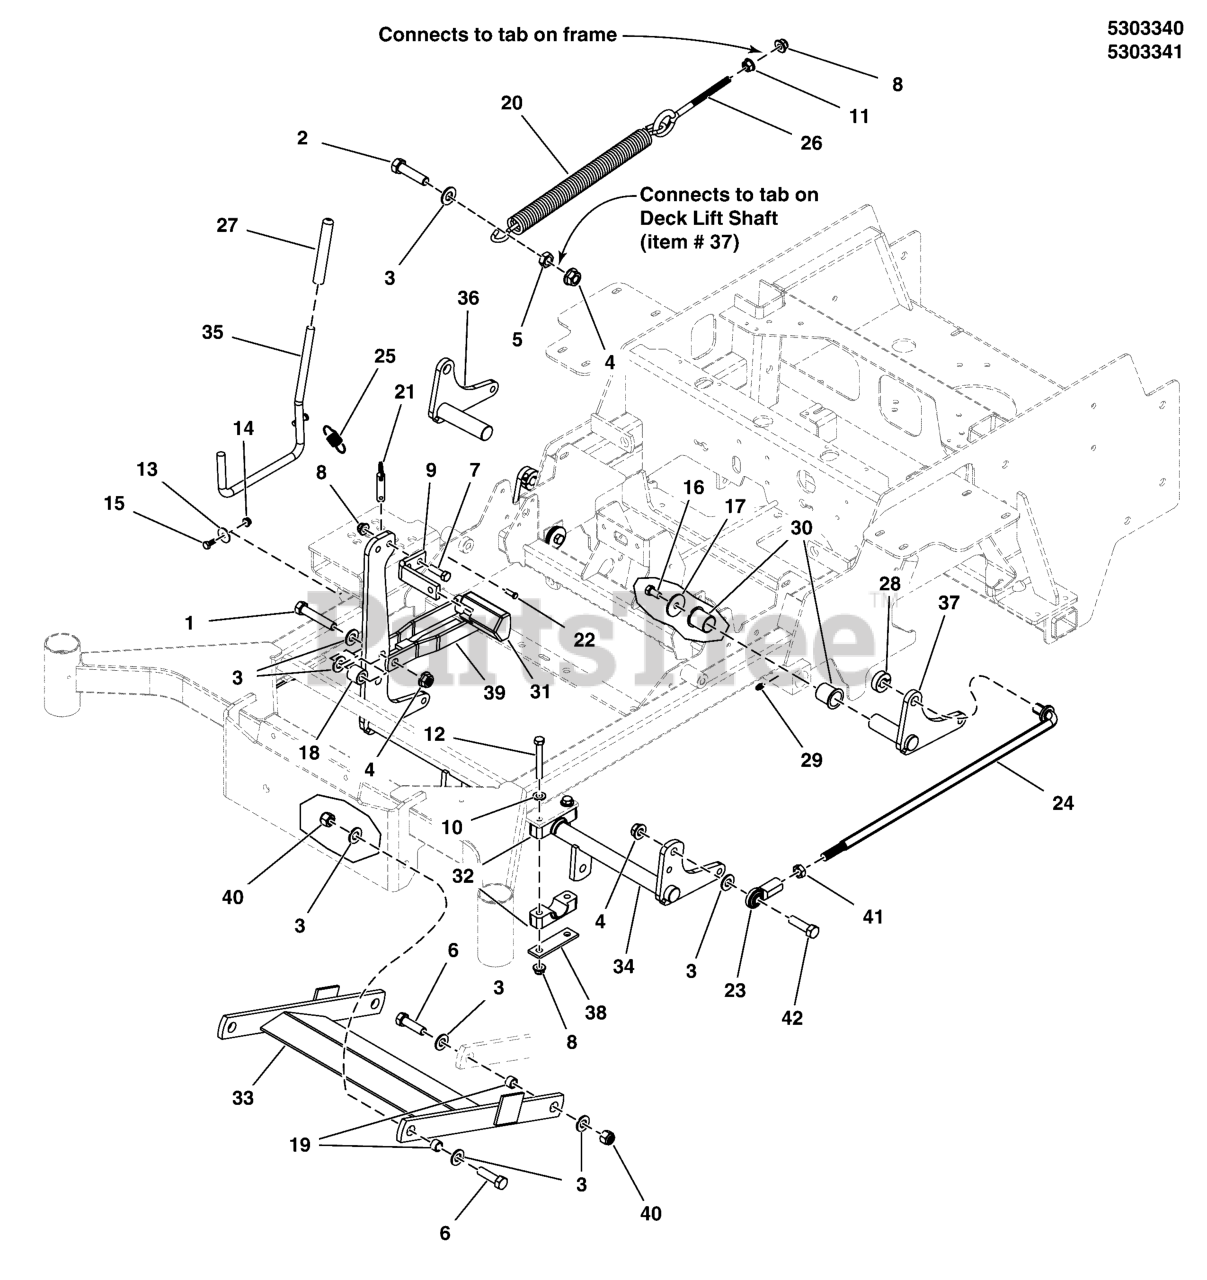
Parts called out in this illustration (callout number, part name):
1	BOLT, 1/2-13 X 2-3/4 GD5 CZ
2	BOLT, 1/2-13 X 2" GD5 CZ
3	WASHER, 1/2 SAE
4	NUT, Hex Flange, Nylock, 1/2-13
5	NUT, 1/2-13 HEX JAM
6	BOLT, 1/2-20 X 1-3/4" GD8 CZ
7	BOLT, 3/8-16 X 1-1/4" GD5 CZ
8	NUT, 3/8-16 HEX NYLOCK FLANGE
9	PEDAL, FOOT - BLK
10	WASHER, 3/8 SAE
11	NUT, 3/8-16 HEX SERRATED FLANGE
12	BOLT, 3/8-16 X 2-3/4" GD5 CZ
13	WASHER, 1/4 FENDER
14	NUT, 1/4-20 HEX NYLOCK FLANGE
15	HHCS, 1/4-20 X 0.625, GR5, ZINC/CLEAR
16	BOLT, 3/8-16 X 3/4, PLT W/PATCH
17	WASHER, .390 X 1.50 X .109, YZ
18	SPACER, .52 X 1.00 X .88, CZ
19	INSERT, BEARING
20	SPRING-EXT, 1.00 ODX13.25LGX.177WR, BLK
21	PIN, HITCH, 1/2 X 2.00 OAL, YP
22	PIN, CLEVIS, 1/4 X 1/2, PLATED
23	JOINT-BALL .500-20 THD .500ID, CLR ZINC
24	ROD, DECK LIFT SNP
25	SPRING-EXT, .740 ODX2.025LGX.072WR, BLK
26	EYE BOLT, 3/8-16 X 6, 3THRD, 1EYE, CZ
26	EYEBOLT, 3/8-16 X 4, 2.13THRD, .75EYE, C
27	GRIP, FOAM, .475 X 4.35 X .095
28	COLLAR, 5/8 SPLIT
29	GREASE FITTING, 1/4-28 STRAIGHT
30	BUSHING, 1.00 X 1.13 X 1.38, PLASTIC
31	PEDAL, Rubber
32	PIVOT BLOCK, PLASTIC
33	WELD, PULLER BAR, S125XT - BLACK
34	WELD, DECK LIFT SHAFT, S125XT - RED
34	WELD, DECK LIFT SHAFT - RED
35	WELD, Rod, Deck Lift - BLK
36	PIVOT, DECK LIFT WELD - RIGHT - BLK
37	PIVOT, DECK LIFT WELD - LEFT - BLK
38	PLATE, PIVOT BLOCK SUPPORT - BLK
40	NUT, Hex, Nylon Lock, 1/2-20
41	NUT, 1/2-20 HEX JAM
42	BOLT, 1/2-13 X 1-3/4 GD5 CZ
